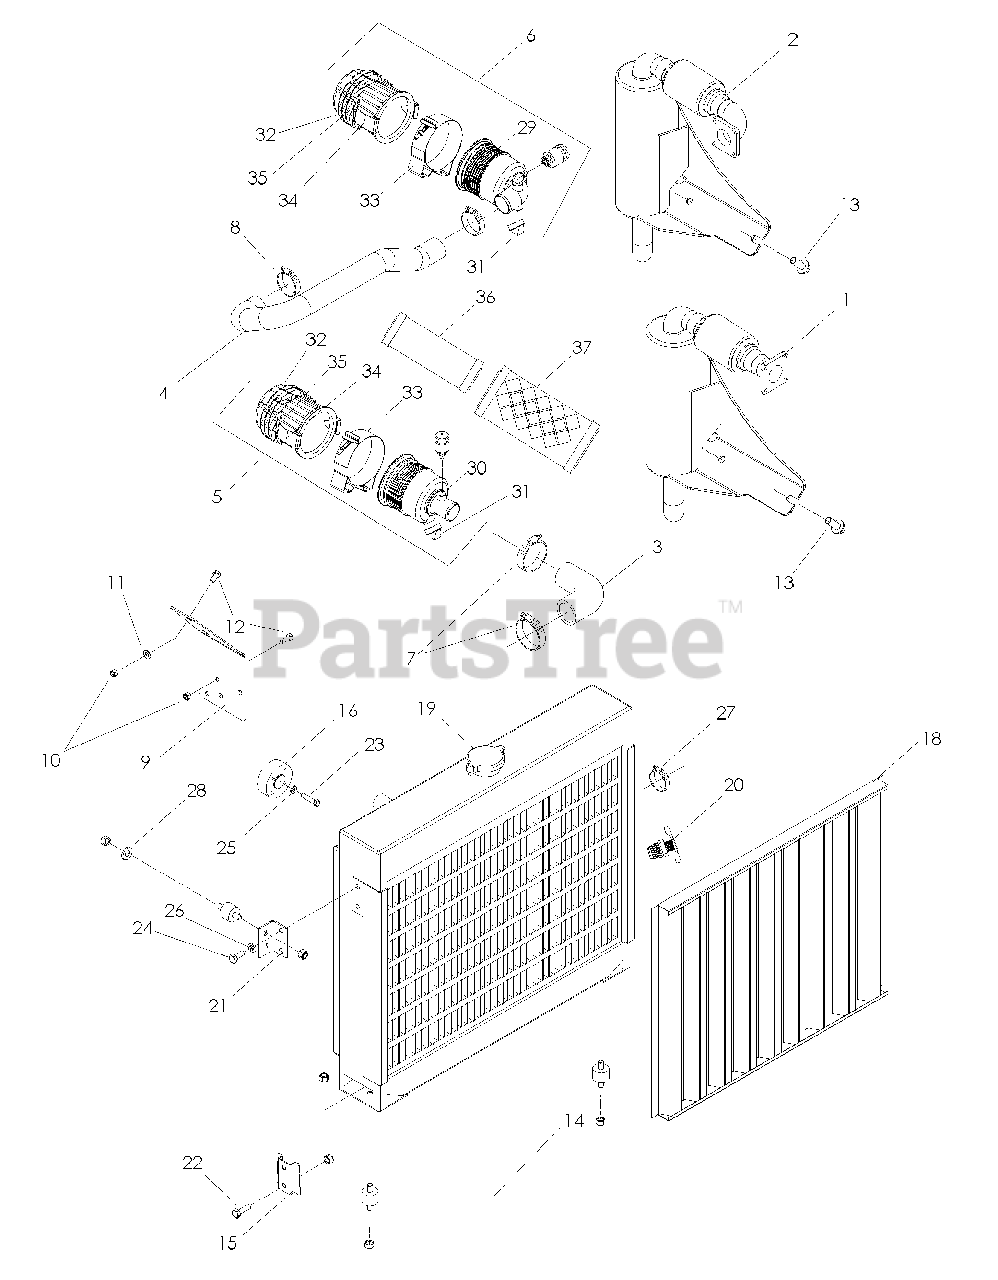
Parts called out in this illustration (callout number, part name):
1	MUFFLER BZ7234D / BZ7234D BF
2	MUFFLER BZ6127D / BZ6127D BF
3	AIR FILTER HOSE BZ7234D / BZ7234D BF
4	AIR FILTER HOSE BZ6127D / BZ6127D BF
5	AIR FILTER ASSEMBLY BZ7234D / BZ7234D BF
6	AIR FILTER ASSEMBLY BZ6127D / BZ6127D BF
7	CLAMP BZ7234D / BZ7234D BF
8	CLAMP BZ6127D / BZ6127D BF
9	BRACKET, AIR FILTER
10	NUT 5/16-18 HEX NYLOC
11	WASHER 5/16 STD FLT
12	HCS 5/16-18 x 3/4
13	BOLT 1/2-13 x 1 1/4 WHIZLK
15	BRACKET, MOUNTING
16	SPACER, FAN BZ7234D / BZ7234D BF
16	SPACER, FAN BZ6127D / BZ6127D BF
17	RADIATOR ASSEMBLY BZ7234D / BZ7234D BF Includes Radiator/Shroud Plus Parts 18-21
17	RADIATOR ASSEMBLY BZ6127D / BZ6127D BF Includes Radiator/Shroud Plus Parts 18-21
18	DEBRIS SHIELD
21	BRACKET, ISO
22	HCS 5/16-18 x 1
23	HCS M6- 1 x 40mm GR88 BZ7234D / BZ7234D BF
23	HCS M6- 1 x 30mm GR88 BZ6127D / BZ6127D BF
24	HCS 5/16-18 x 3/4
25	WASHER 1/4 SPLIT LOCK
26	WASHER 5/16 SLOTTED LOCK
27	CLAMP, HOSE
28	WASHER 5/16 FLAT SAE
29	AIR FILTER ASSM, UPPER BZ6127D / BZ6127D BF
30	AIR FILTER ASSM, UPPER BZ7234D / BZ7234D BF
32	AIR FLTR ASSM, LOWER
33	BRACKET, MOUNTING
36	ELEMENT, SAFETY
37	FILTER, AIR
